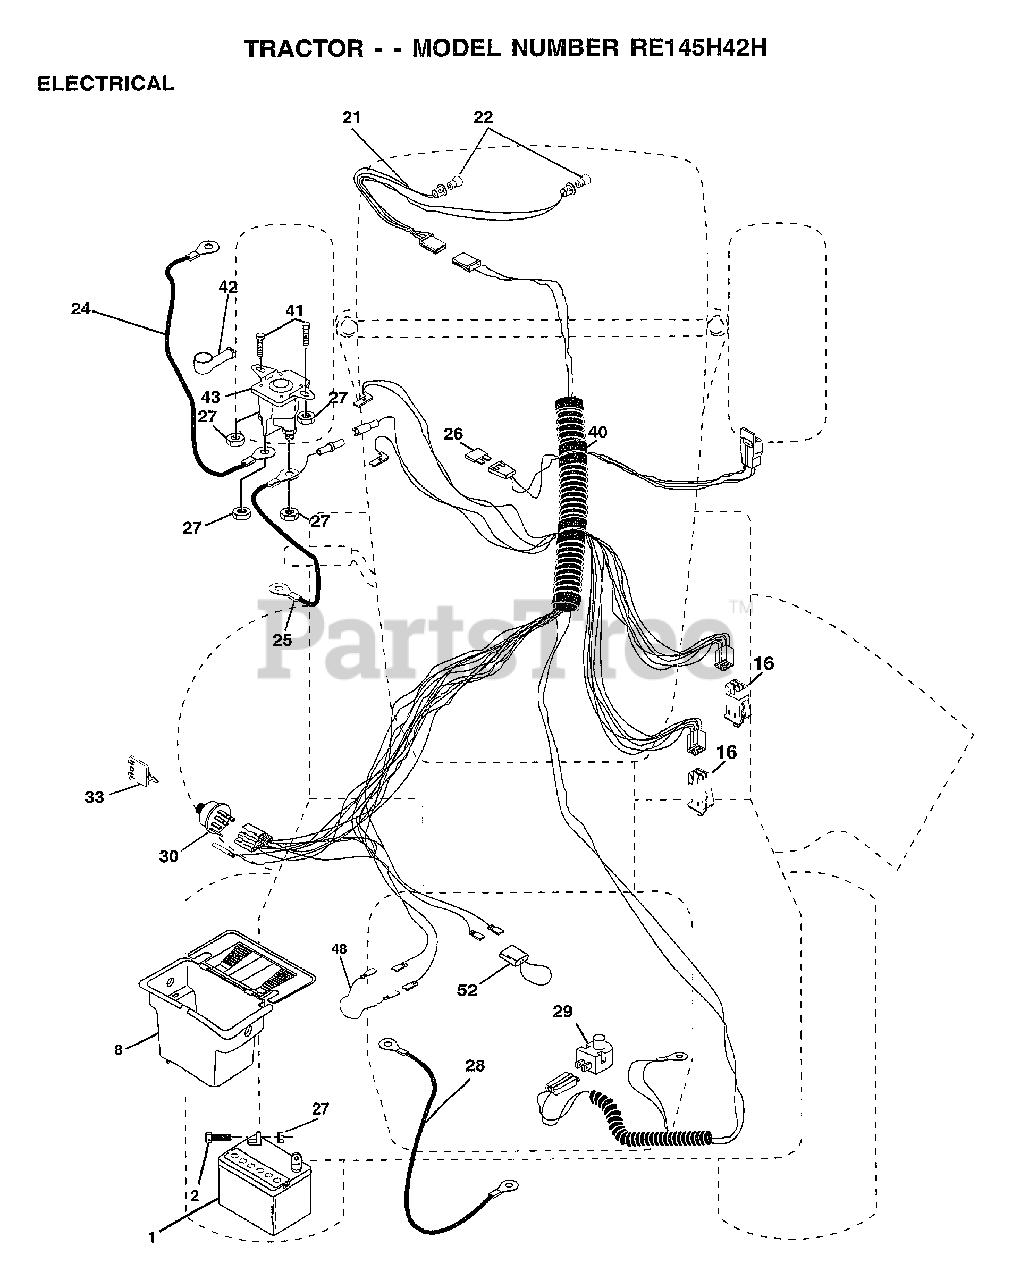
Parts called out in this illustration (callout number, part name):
2	BOLT LT
8	"CASE,BATTERY.MECH"
16	SWITCH INTERLOCK
21	HARNESS.ASM.LIGHT W/4152J
22	HEADLAMP BULB
24	"CABLE T, BATTERY"
25	CABLE.BTRY.6GA.RD
26	FUSE.15 AMP
27	NUT
28	CABLE T
29	SWITCH SEAT
30	SWITCH.IGN.
33	KEY MLD GEN DELTA
40	HARNESS IGN
41	BOLT HXHD FIN
48	ADAPTER AMMETER
52	PROTECTION LOOP
